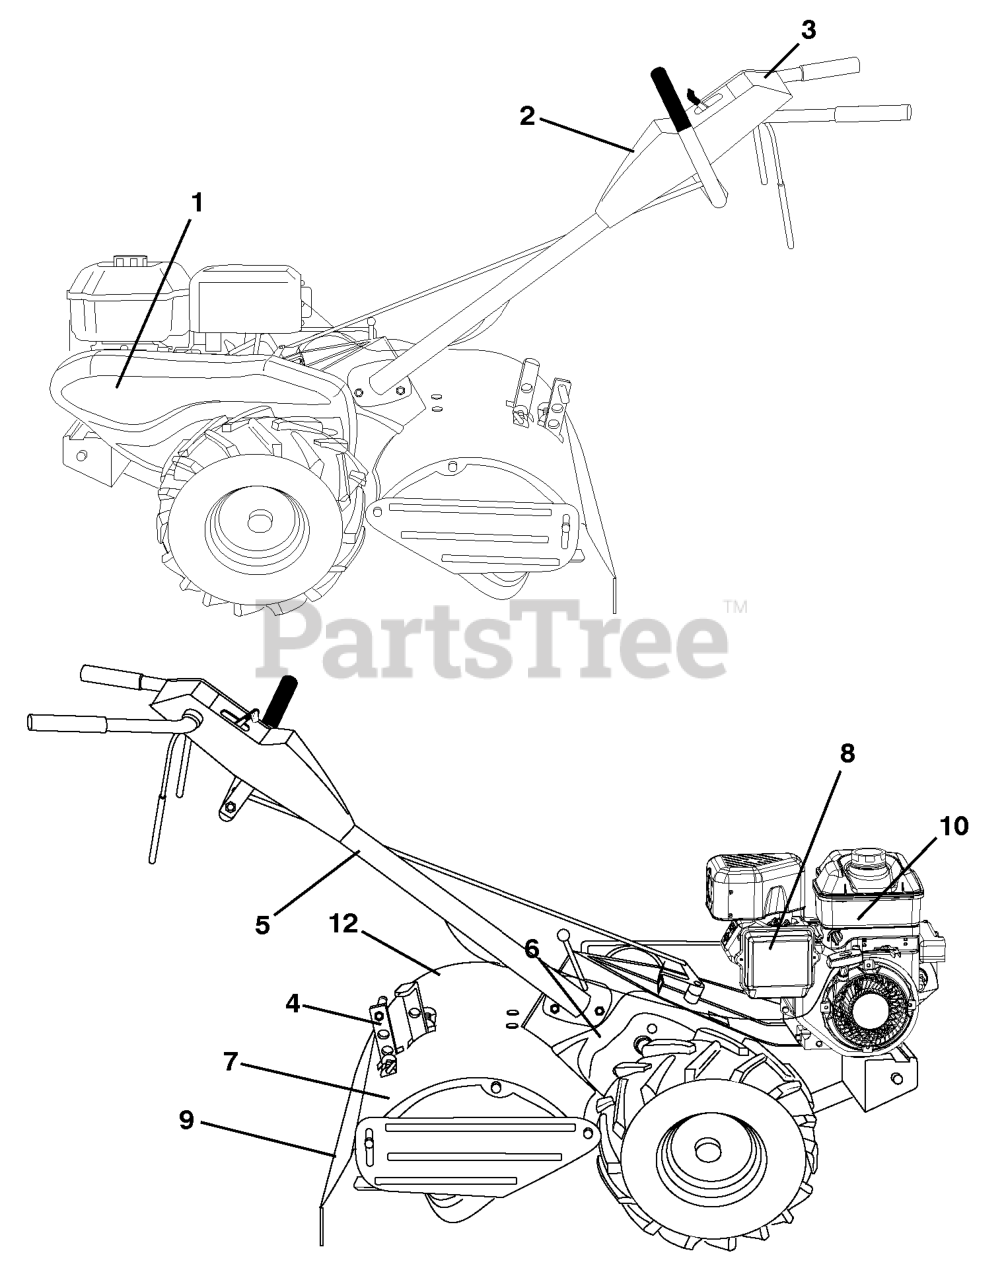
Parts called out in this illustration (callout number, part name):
1	RP.DECAL.BADGE.170MM.TEXTLOGO
2	DECAL.CONSOLE.DRT900E.HUSQ
3	DECAL.TILLER.CNSL.INS.
4	DECAL.SHIELD.TN.DRT17.HUSQ.008
5	DECAL TI (2 2)
6	DECAL.SHIFT.INDICATOR.DRT
7	DECAL.REVERSE.HUSQ
8	DECAL.B&S.900.A/S.C (279005)
9	DECAL.DRT.WARN.ENG/F
10	DECAL.B&S.900.TANK.REF.276991
12	DECAL.FORWARD.HUSQ
